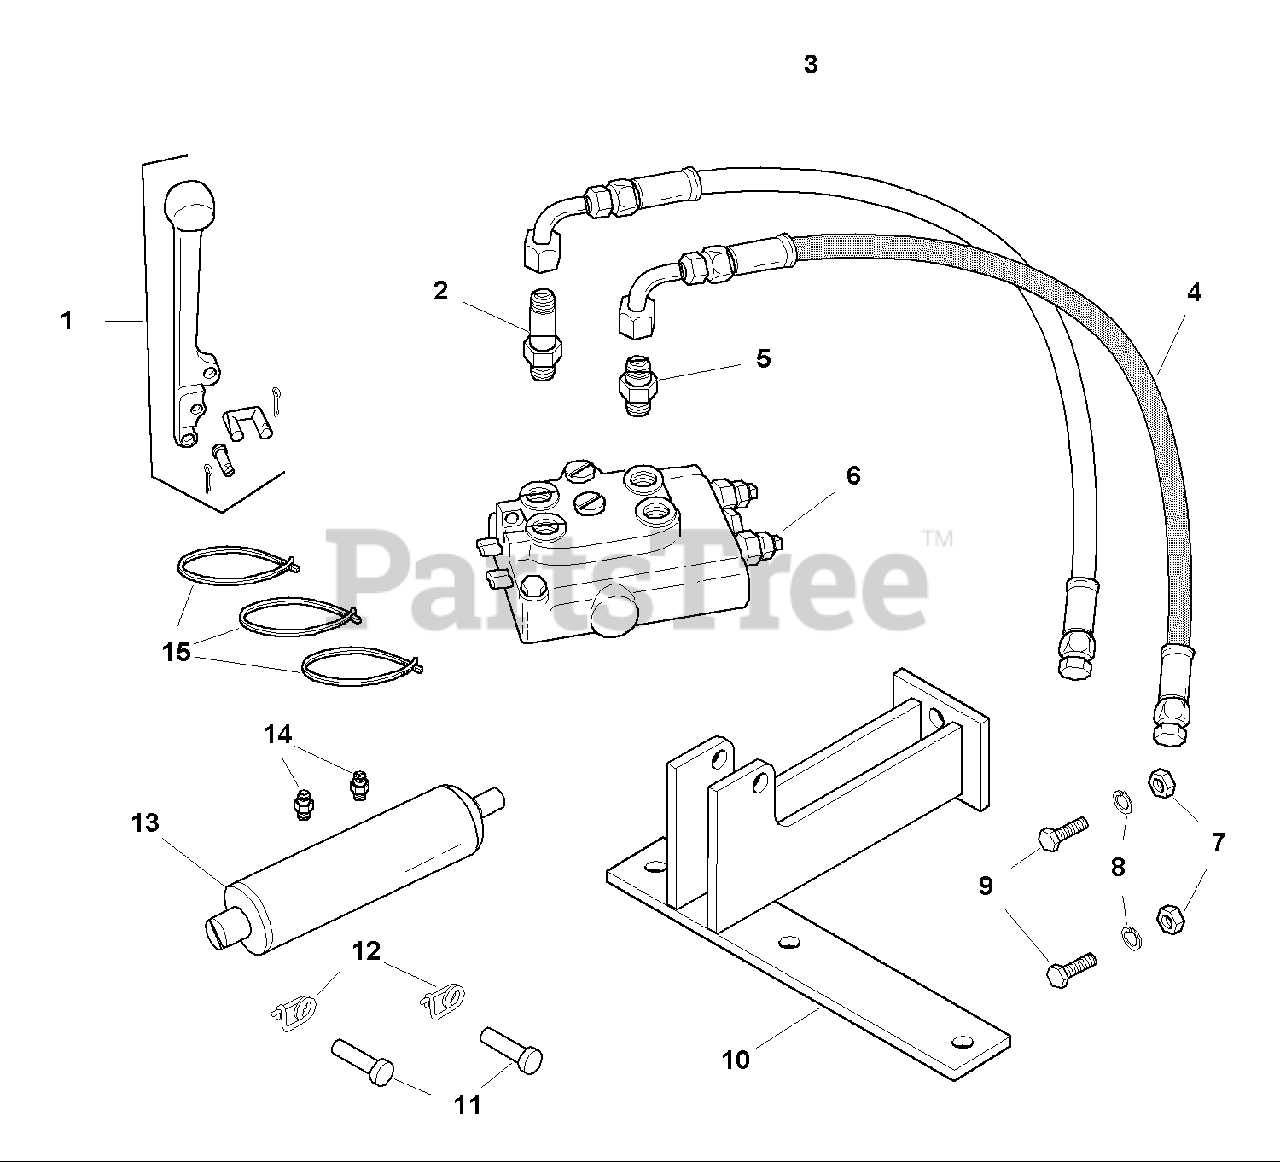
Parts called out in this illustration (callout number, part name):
1	LEVER, LINK & PIN ASSEMBLY
2	FITTING, Male
3	HOSE ASSEMBLY, 67" Long w/Fitting
4	HOSE ASSEMBLY, 69" Long w/Fitting
5	FITTING, Male
6	VALVE ASSEMBLY
7	NUT, Hex 1/2-13
8	LOCKWASHER, 1/2
9	CAPSCREW, Hex Head, 1/2-13 x 1-1/2
10	SUPPORT ASSEMBLY
11	PIN, Clevis
12	RETAINER, Pin, Spring
13	CYLINDER ASSEMBLY
14	FITTING, Male
